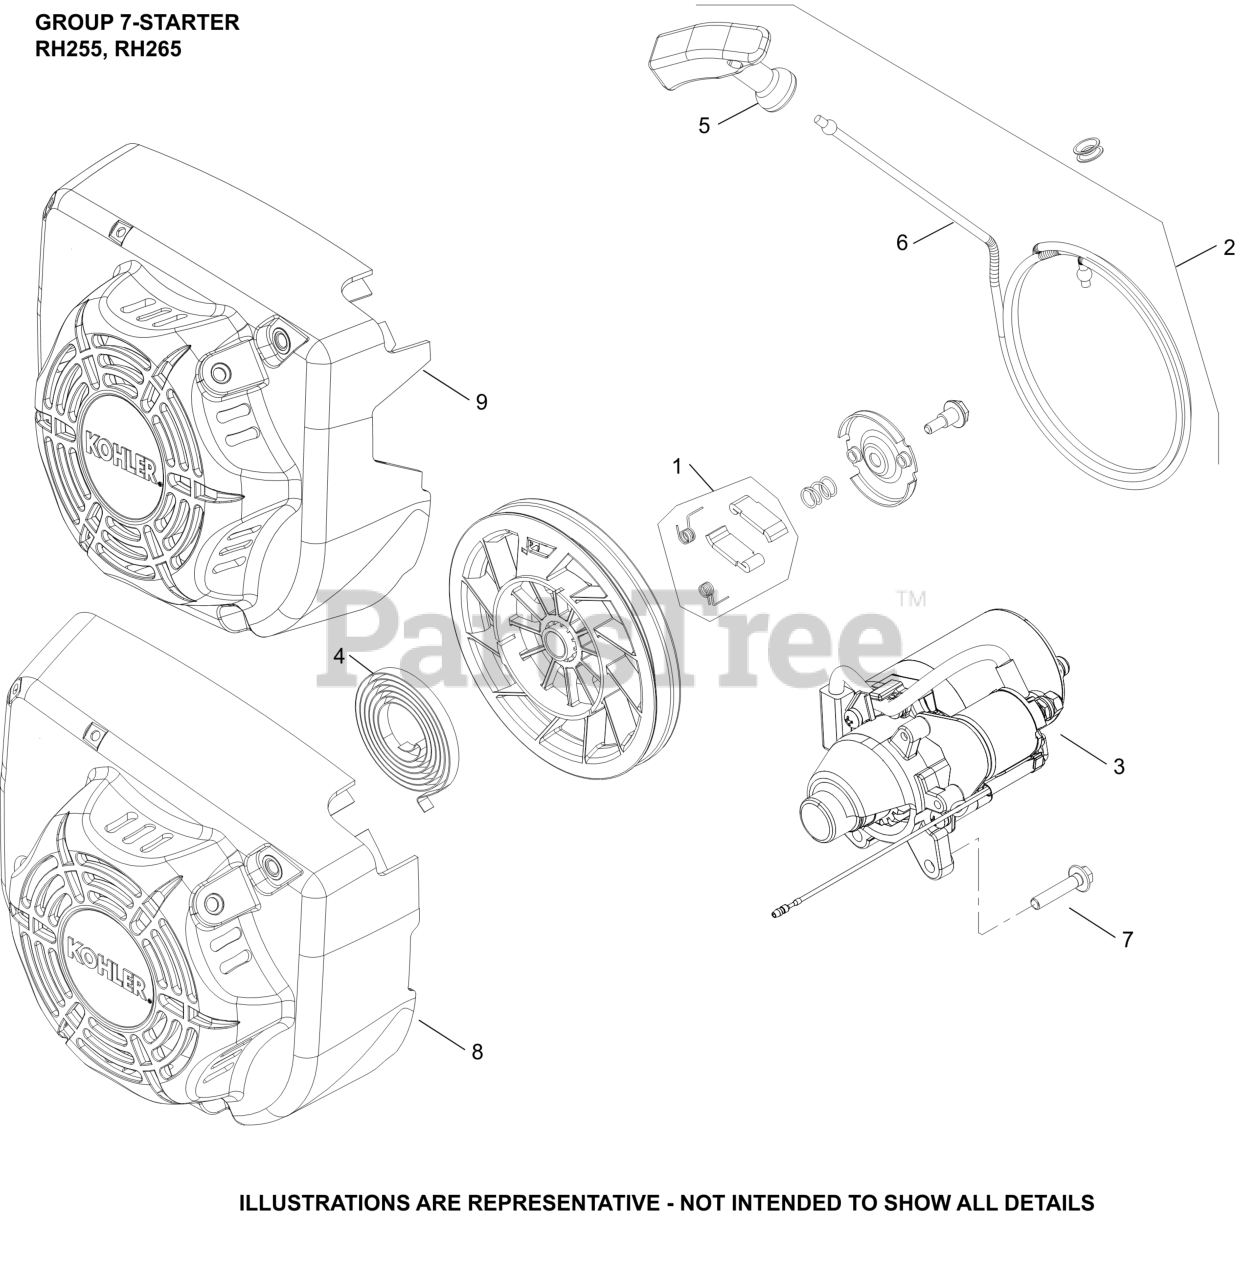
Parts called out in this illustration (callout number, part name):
5	HANDLE, RECOIL STARTER
6	ROPE, STARTING
8	COVER, RECOIL ASSEMBLY-DISCONTINUED
